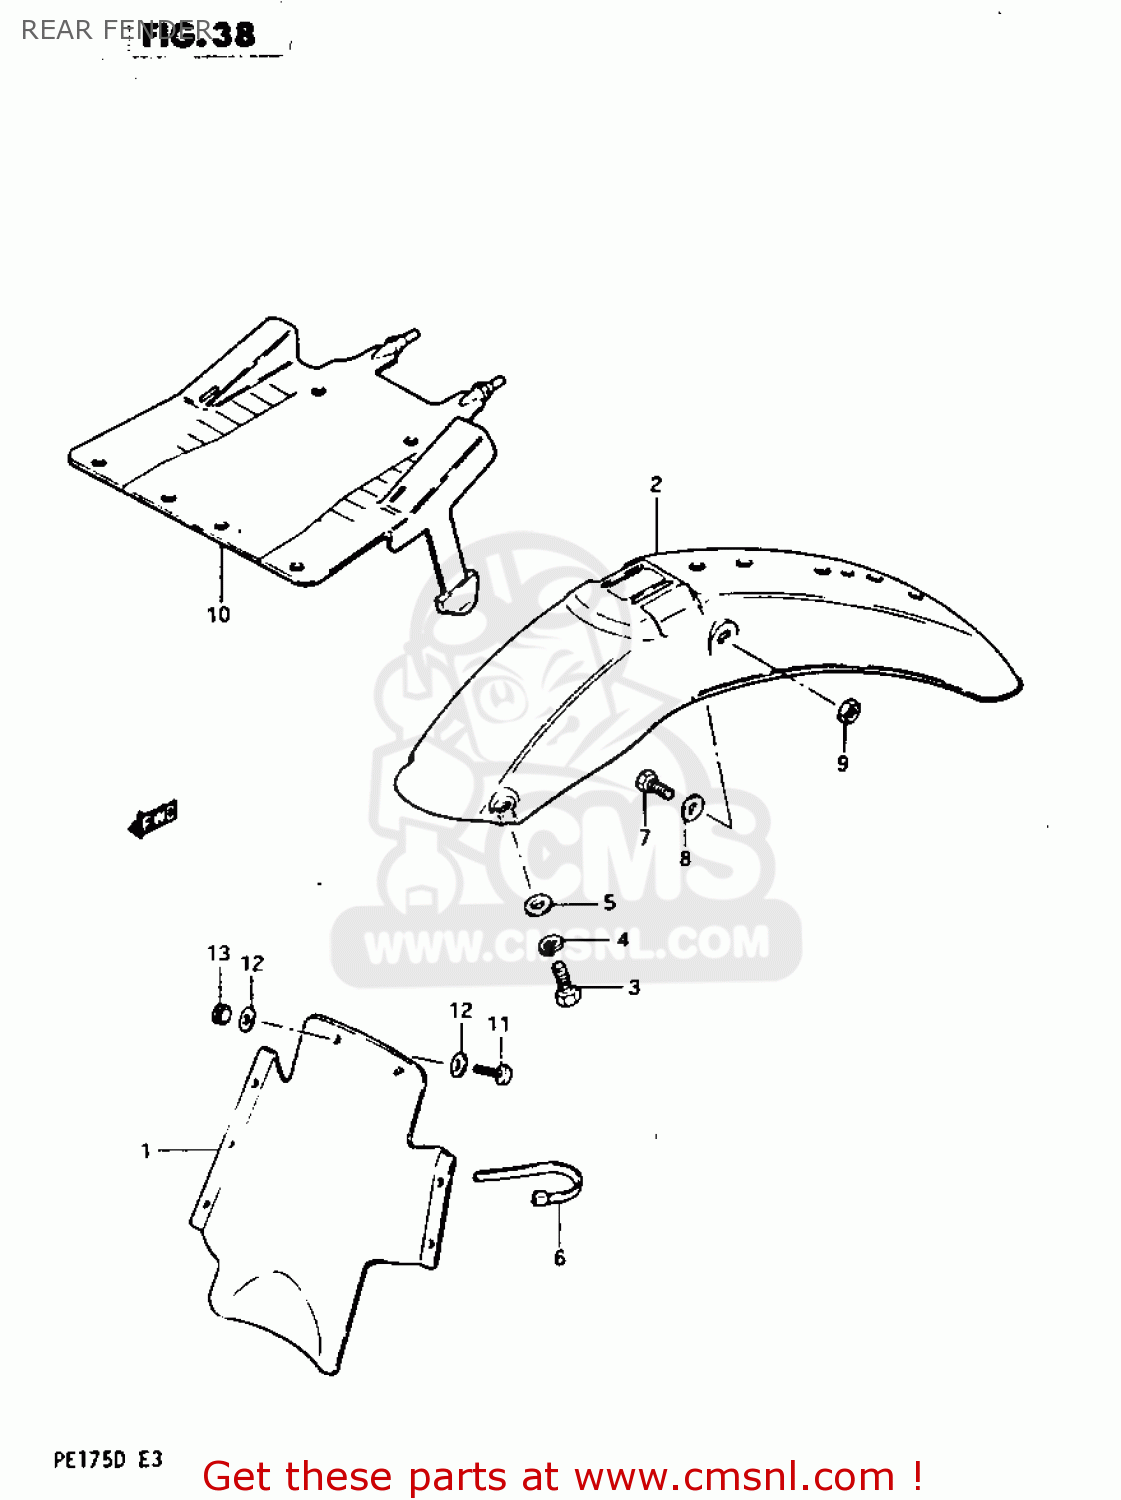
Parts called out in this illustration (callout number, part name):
1	FENDER,RR FR
2	FENDER,REAR
3	BOLT
4	WASHER,LOCK
5	WASHER
6	CLAMP
7	SCREW
8	WASHER (6.5X20X1.2)
9	NUT
10	GUIDE,RR FENDER MUD
11	SCREW
12	WASHER
13	NUT
